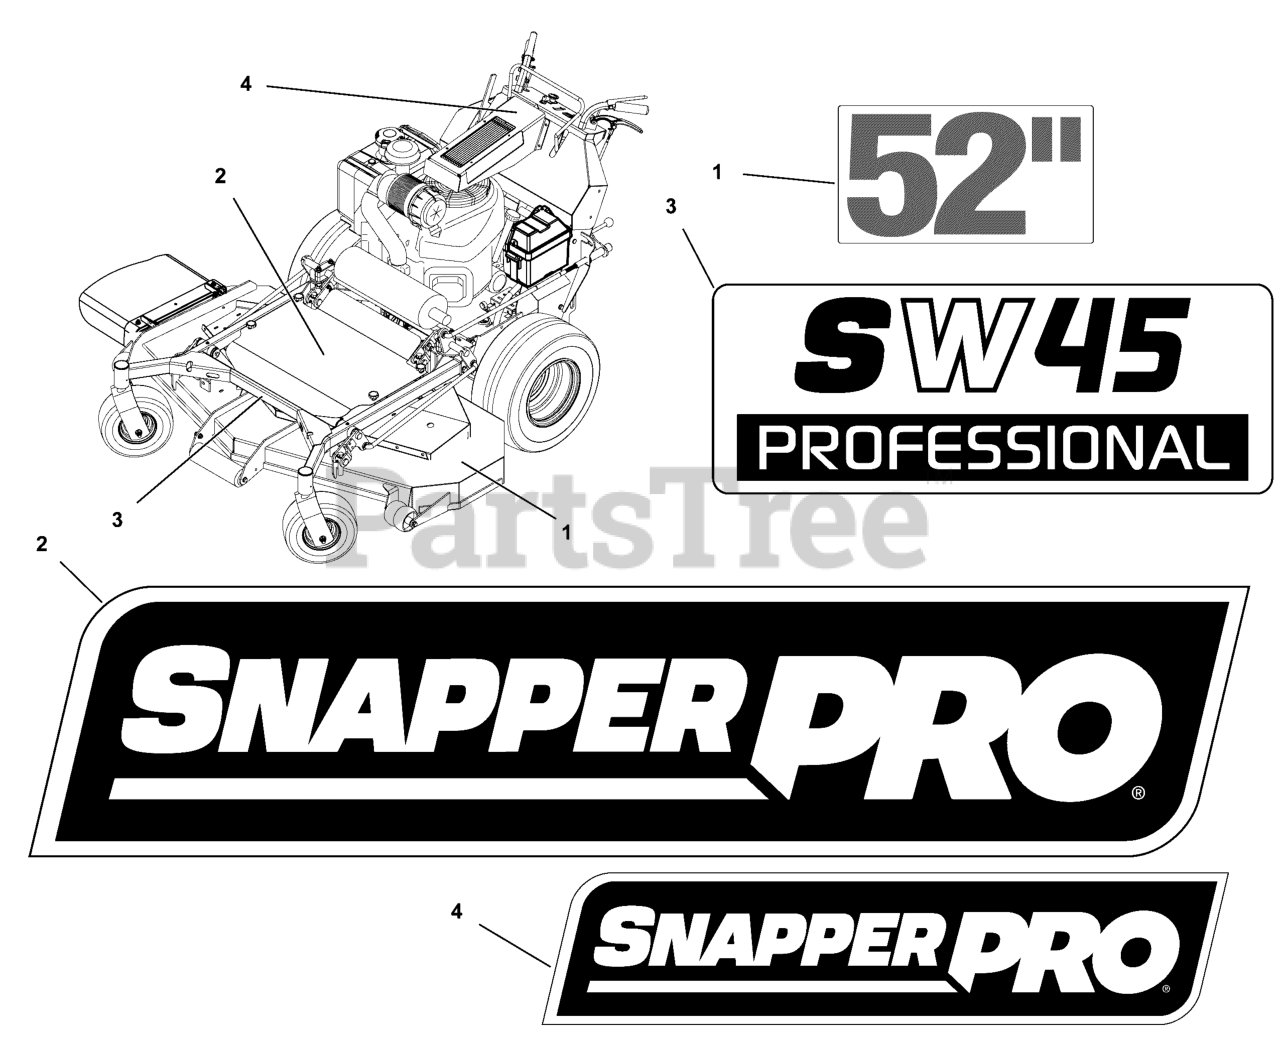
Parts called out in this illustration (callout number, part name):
1	DECAL, 52
2	DECAL, SNAPPER PRO LOGO, LARGE
3	DECAL, MODEL, SW45
4	DECAL, SNAPPER PRO LOGO, X-SMALL
